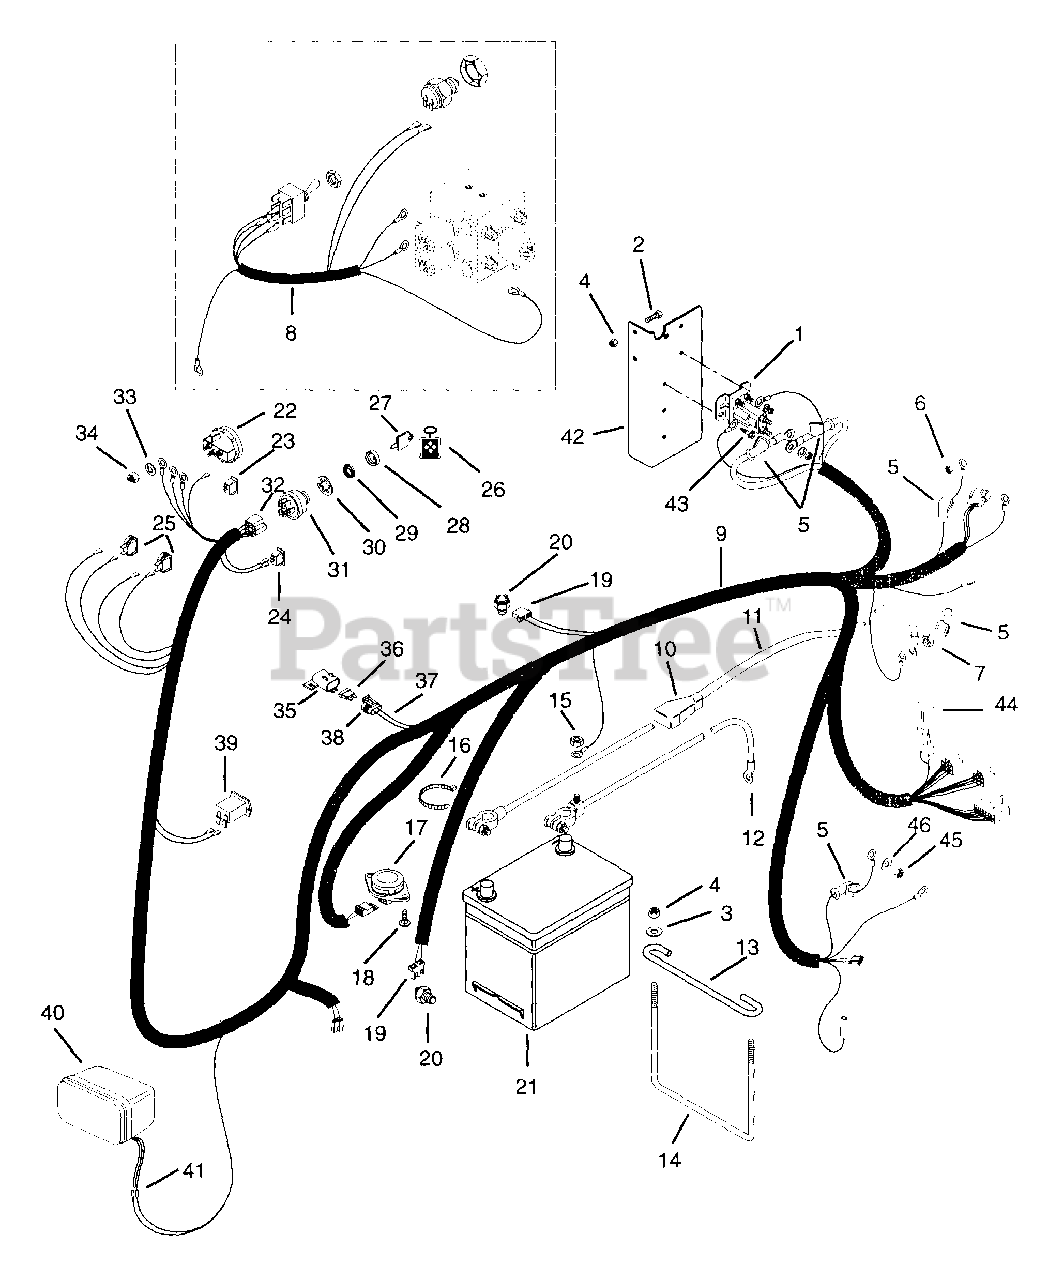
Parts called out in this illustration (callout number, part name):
1	Solenoid
2	Bolt-Hex .25-20 x .75 Grade 5
3	Washer-Flat-Steel .281 x .625 x .065
4	Nut-Locking-Nylon .250-20 Grade 2
5	Boot, Insulator
6	Nut-Hex M5 x .8
7	Nut-Hex M8 x 1.25
8	Wire Harness, 4 Wheel Drive Kit (054,303)
9	Wire Harness, Kubota
10	Cover, Battery Terminal
11	Cable, Positive Cable
12	Cable, Negative Battery
13	Rod, Hold Down
14	Rod, Battery
15	Nut-Hex .312-18 Grade 2
16	Tie Wrap, Black
17	Seat Switch
18	Screw-Machine .25-20 x .50
19	Connector, 2-Wire Switch
20	Switch-Neutral Start
21	Battery, 24F
22	Gauge, Temperature
23	Cover-Switch
24	Switch-Light
25	Light, Indicator
26	Key Chain
27	Ignition Switch Key
28	Cap-Ignition Switch
29	Nut-Panel .562-24
30	Washer-Lock Internal .563 x .040
31	Switch, Ignition (Diesel)
32	Connector
33	Washer-Lock 10 x .047
34	Nut-Hex 10-32
35	Cover
37	Terminal For 14-16 Gauge Wire
38	Assembly, Connector Weather Tight
39	Hour Meter
40	Headlamp, 3 x 5 Halogen
41	Terminal, Male
42	Harness Bracket
43	Screw-Tapping .25-20 x .50
44	Diode
45	Nut-Hex M6 x 1.0
46	Washer-Flat-Steel .281 x .620 x .065
